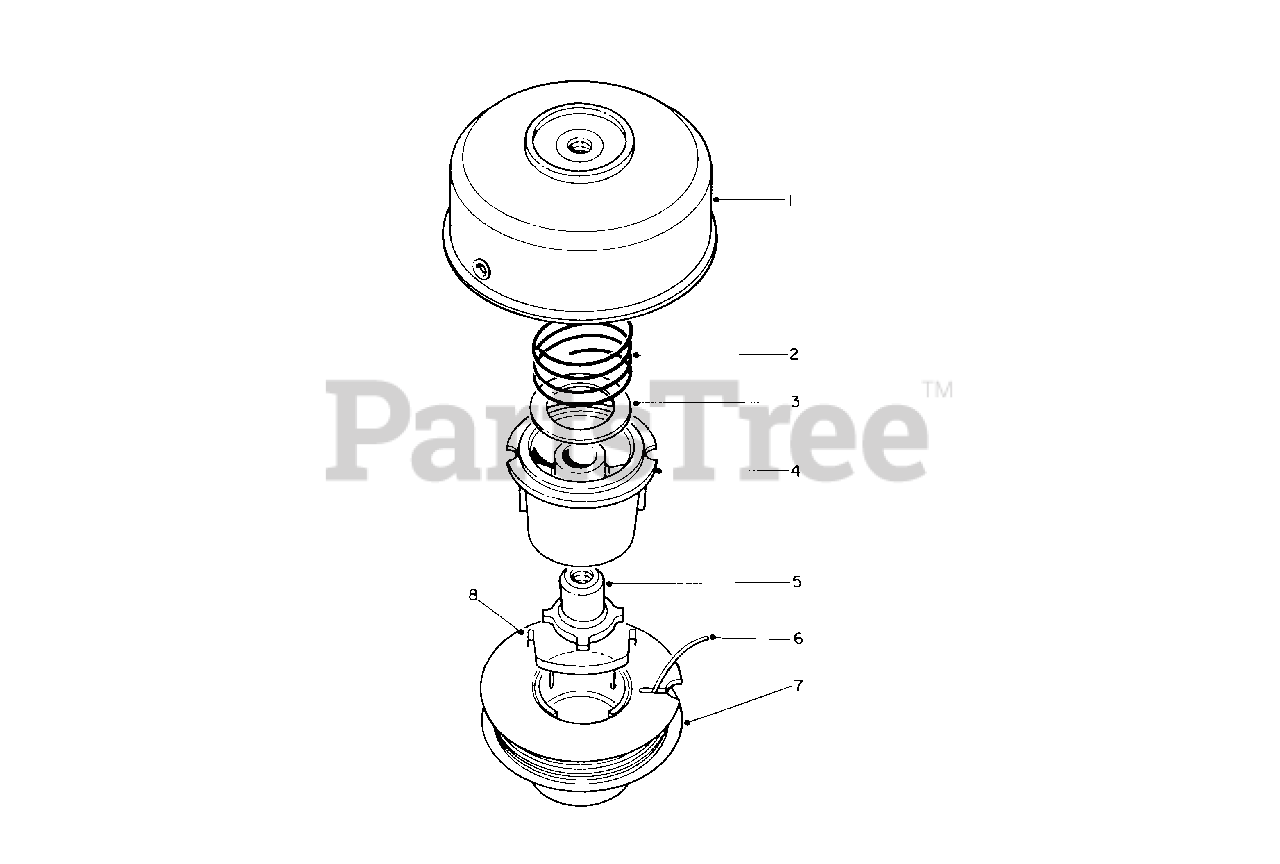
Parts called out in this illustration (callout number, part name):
1	Drum w/Eyelet
4	Core-Spool
5	Driver L.H.
6	Line-Cutting .095 Dia.
7	Spool Prewound .95 Dia. 30' (Incl. Ref. #8)
8	Saddle-Spool Cap
